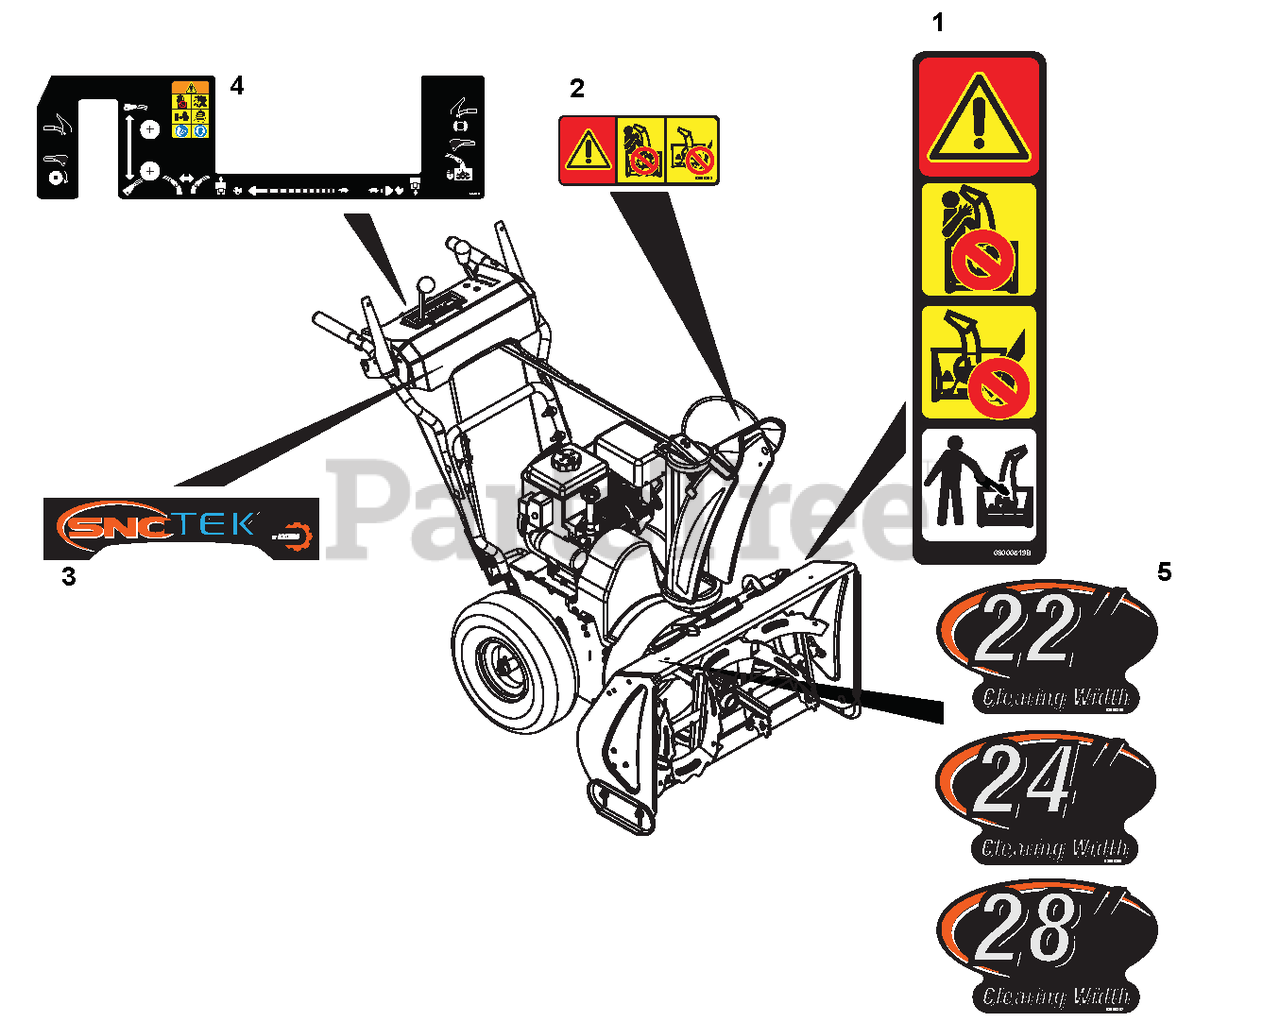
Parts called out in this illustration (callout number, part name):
1	DECAL, DANGER - ROTATING PARTS
2	DECAL, DANGER SNO-TEK
3	DECAL, DASH - SNO-TEK
4	DECAL,CONTROL - COMPACT REMOTE
5	DECAL, HOUSING SNO-TEK 24
